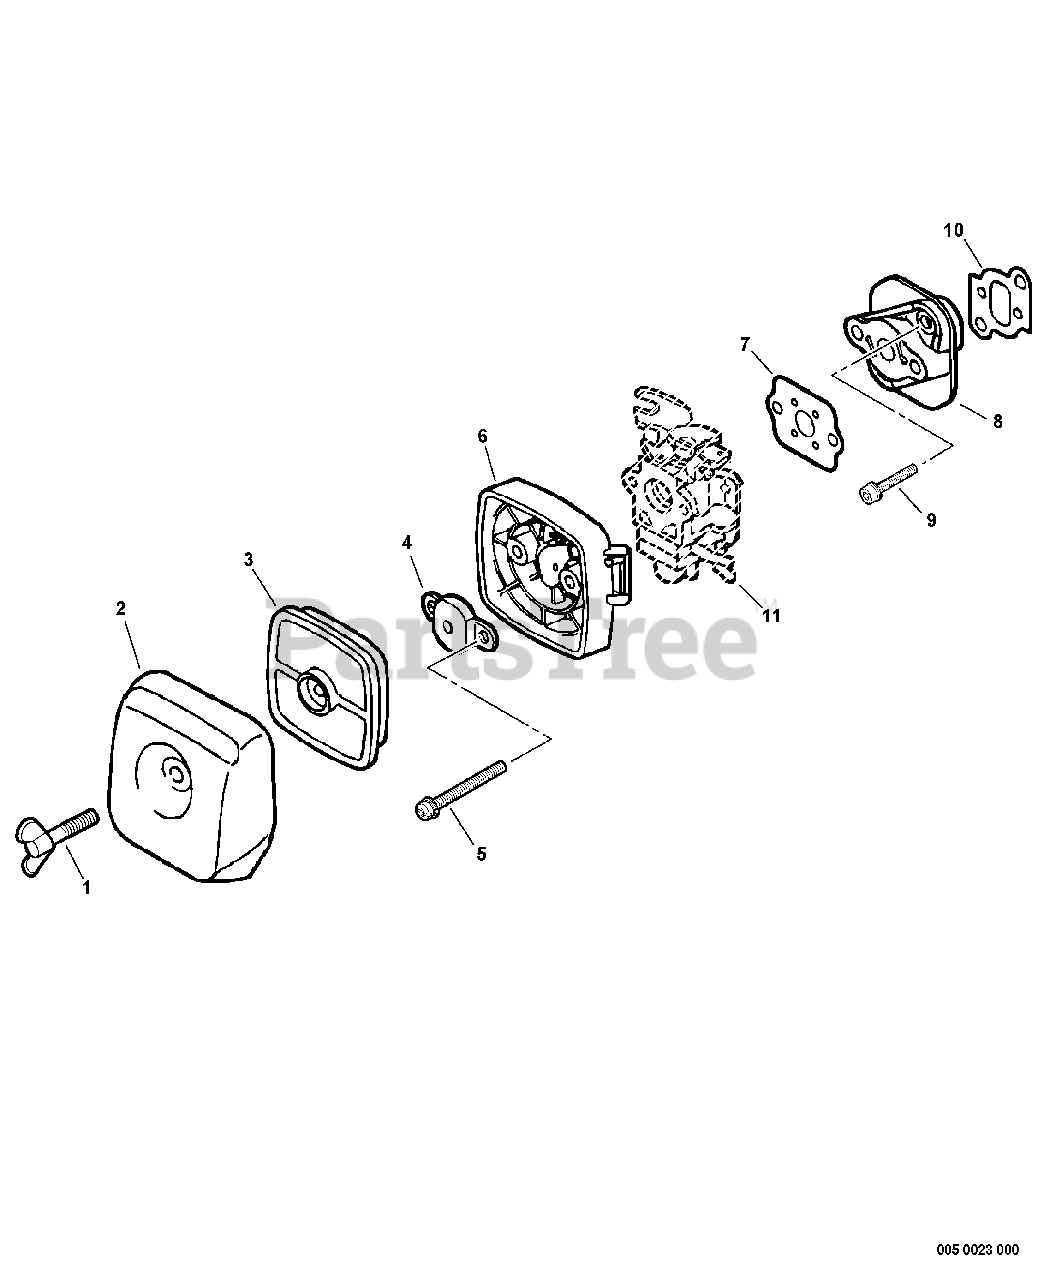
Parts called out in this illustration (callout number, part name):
1	THUMBSCREW
2	COVER, AIR FILTER - GRAY
3	FILTER, AIR - SINGLE LAYER
4	PLATE, PREVENT
5	SCREW - 5X60
6	CASE, AIR FILTER - GRAY
7	GASKET, INTAKE
8	INSULATOR, INTAKE
9	SCREW - 5X25
10	GASKET, INTAKE
11	CARBURETOR
12	RePower TUNE-UP KIT
13	RePower TUNE-UP KIT
